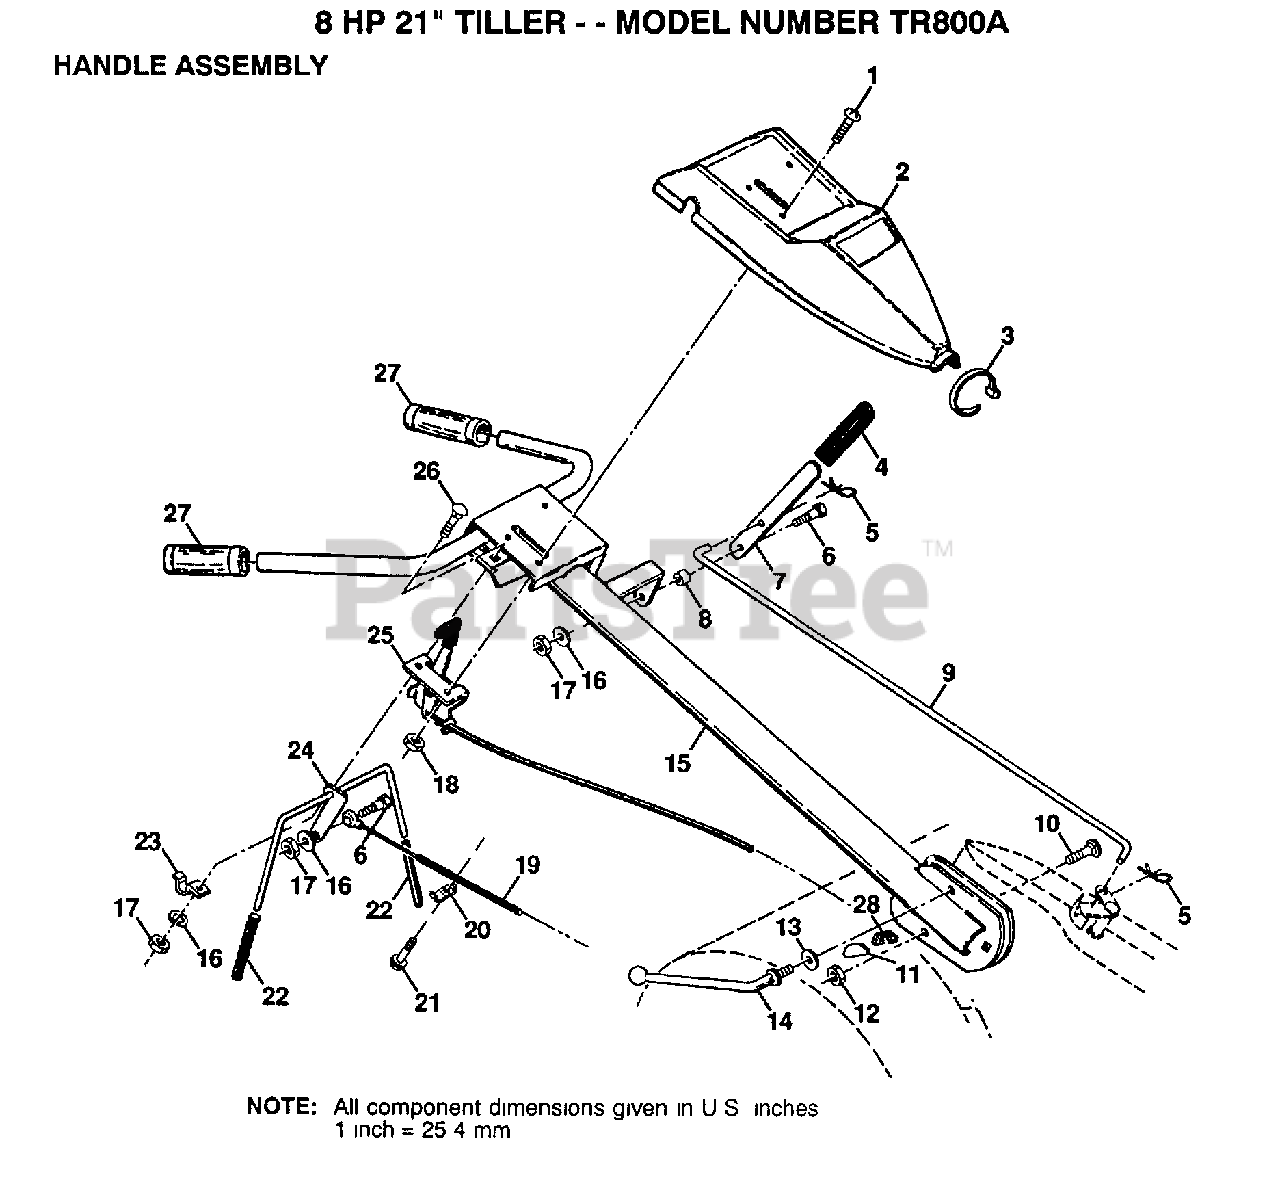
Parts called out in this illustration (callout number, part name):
1	SCREW
2	"PANEL,CONT TI"
3	TIE CABLE CRT
4	GRIP T
5	RETAINER M
6	SHOULDER BOLT ST
7	SHIFT HANDLE CRT
8	GROMMET CRT
9	ROD.SHIFT
10	BOLT, CARRIAGE
11	LOCK CRT
12	LOCKNUT
13	WASHER CRT
14	LEVER LOCK CRT
15	HANDLE.ASM
16	LOCKWASHER
17	NUT, HEX 1/4-20 UNC
19	CABLE-CLUTCH CRT
20	CONDIUT CLIP T
22	GRIP BAR CRT
24	"ASSY CONTROL, BAR"
25	CONTROL.THROTTLE
26	BOLT
28	LOCK.HANDLE
